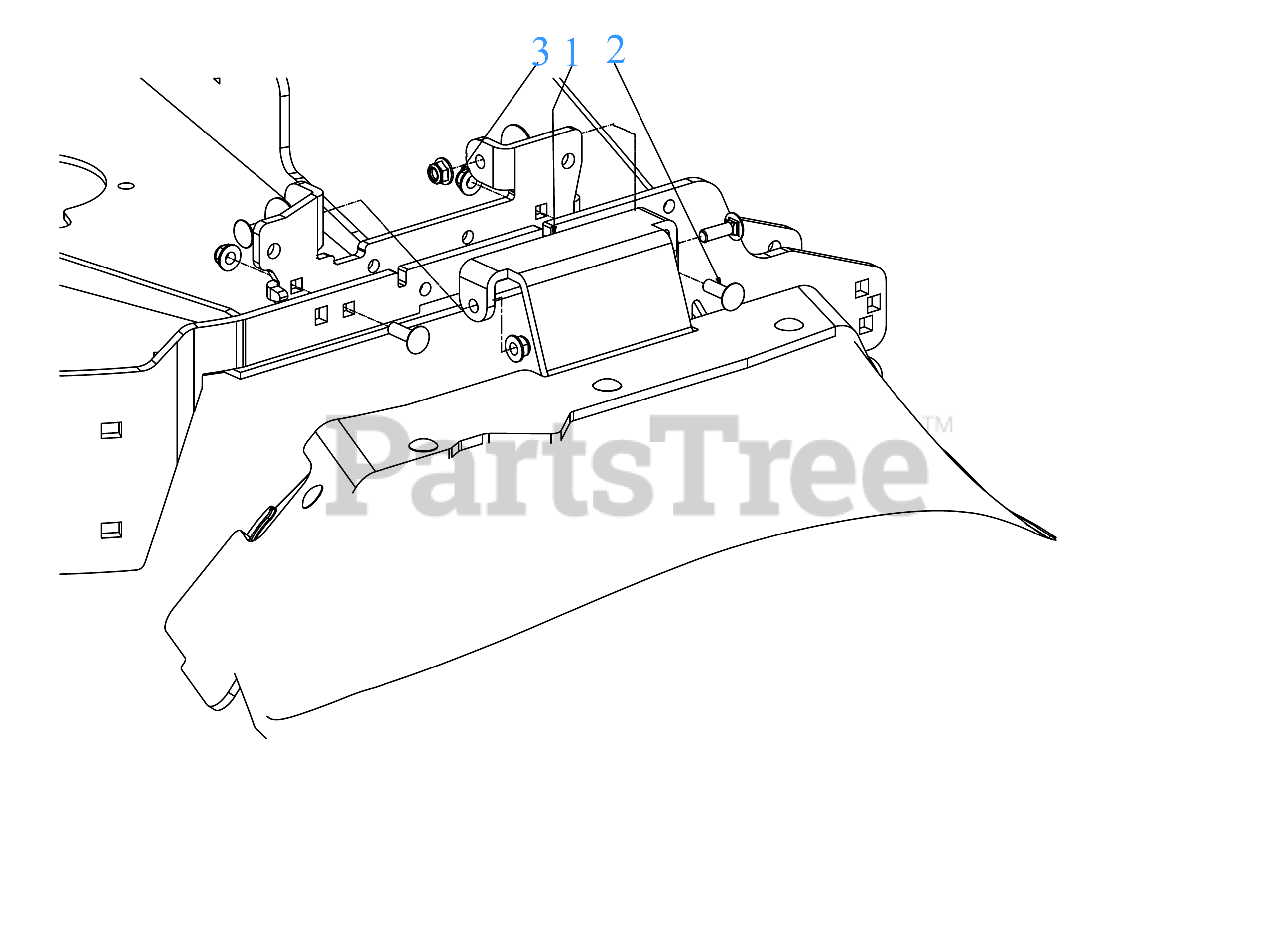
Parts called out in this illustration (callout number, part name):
1	72" DECK CHUTE ASSEMBLY
2	CARRIAGE BOLT 5/16-18 x 1.00
3	FLANGE LOCK NUT 5/16-18
